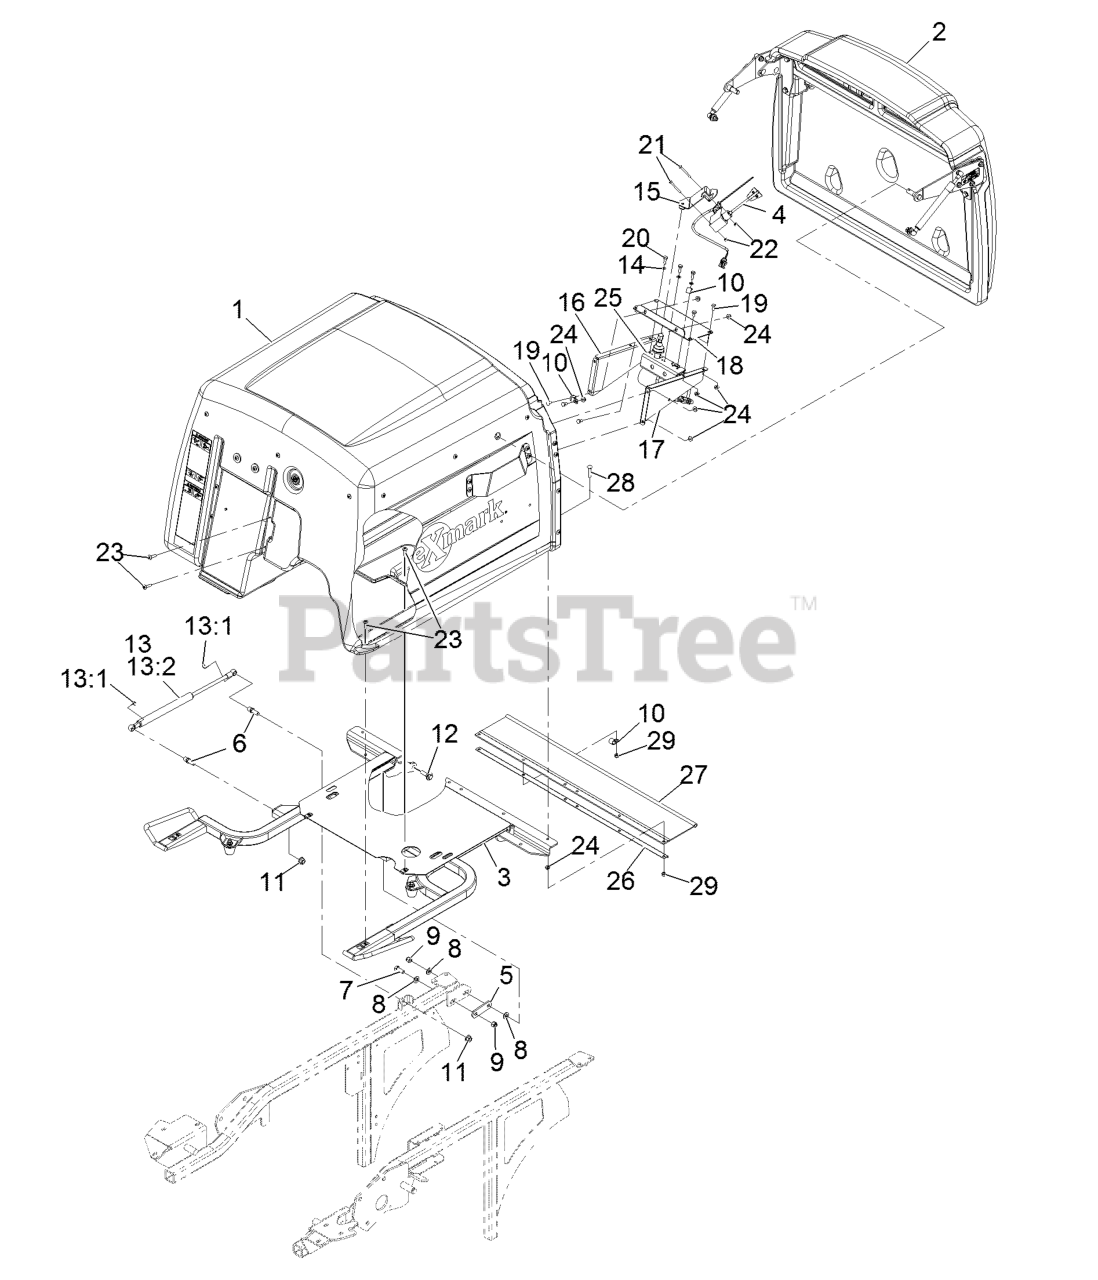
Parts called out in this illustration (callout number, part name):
1	ASM,HOPPER
2	ASM,DOOR HOPPER
3	HOPPER FRAME ASM
4	ASM,FILL SENSOR
5	ARM-LIFT, DECK
6	STUD-BALL
7	SCREW-HH
8	WASHER-FLAT
9	NUT-LOCK, NI
10	CLIP-LOOM
12	SCREW-SHOULDER, HWH
13	DAMPER KIT
13:1	CLIP-RETAINER
13:2	SHOCK-COMPRESSION, GAS
14	WASHER-SPRING
15	MOUNT-SWITCH
16	BRACKET-DRIVE MOTOR, LH
17	BRACKET-DRIVE MOTOR, RH
18	PLATE-SWITCH
19	SCREW-HH
20	SCREW-HH
21	SCREW-PPH
22	NUT-LOCK, NI
23	SCREW-TTH
25	KIT,FILL SENSOR MOTOR
26	CHANNEL-FRAME, HOPPER
27	DEFLECTOR-GRASS
28	SCREW-CARR
29	NUT-LOCK, NI
